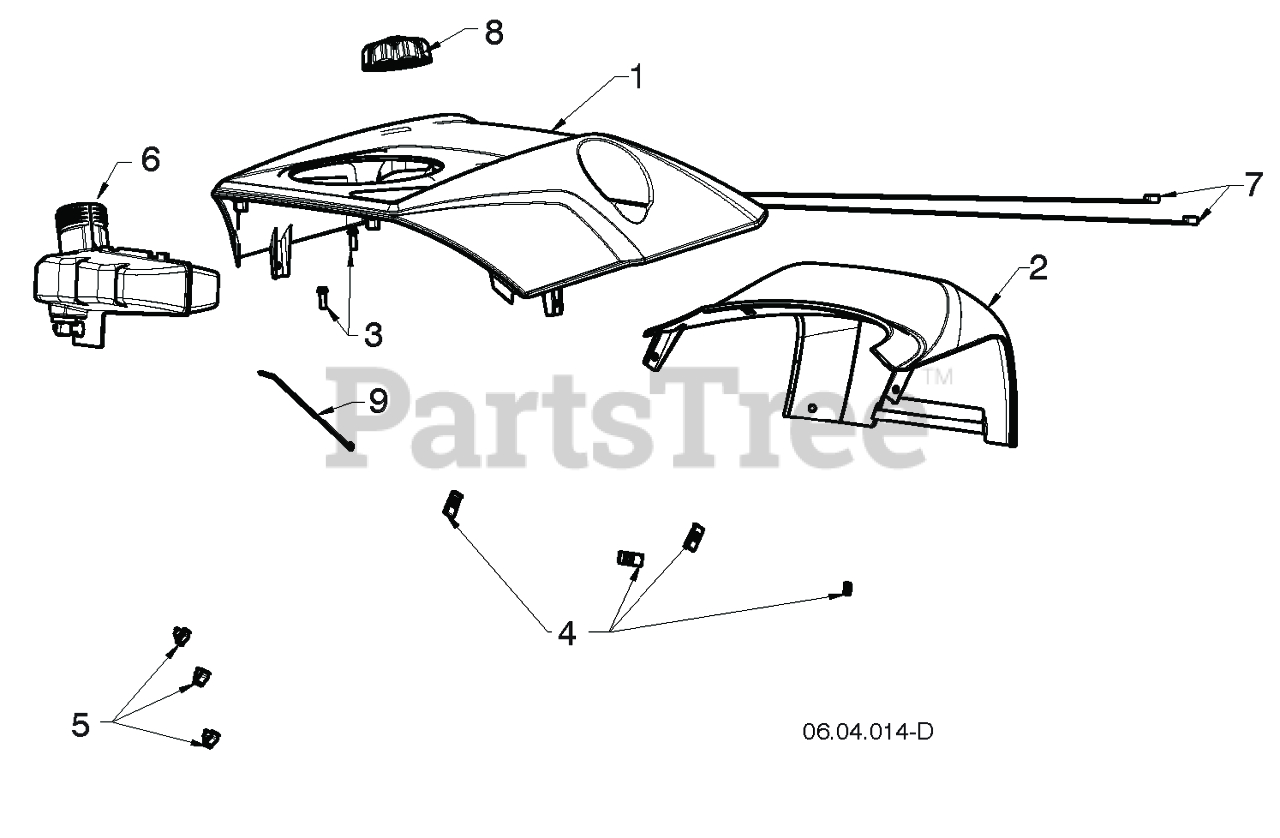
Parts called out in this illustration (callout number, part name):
1	COVER TOP.COVER
2	COVER TOP.REAR.COVER
3	SCREW.HX.13X.750
6	RP_TANK.GAS.12.SINGLE.STAGE.SN
7	TIE.CABLE.24.5X.29.NYLON.WHITE
8	CAP.2.25'.VENTED.RATCHET.EPA
